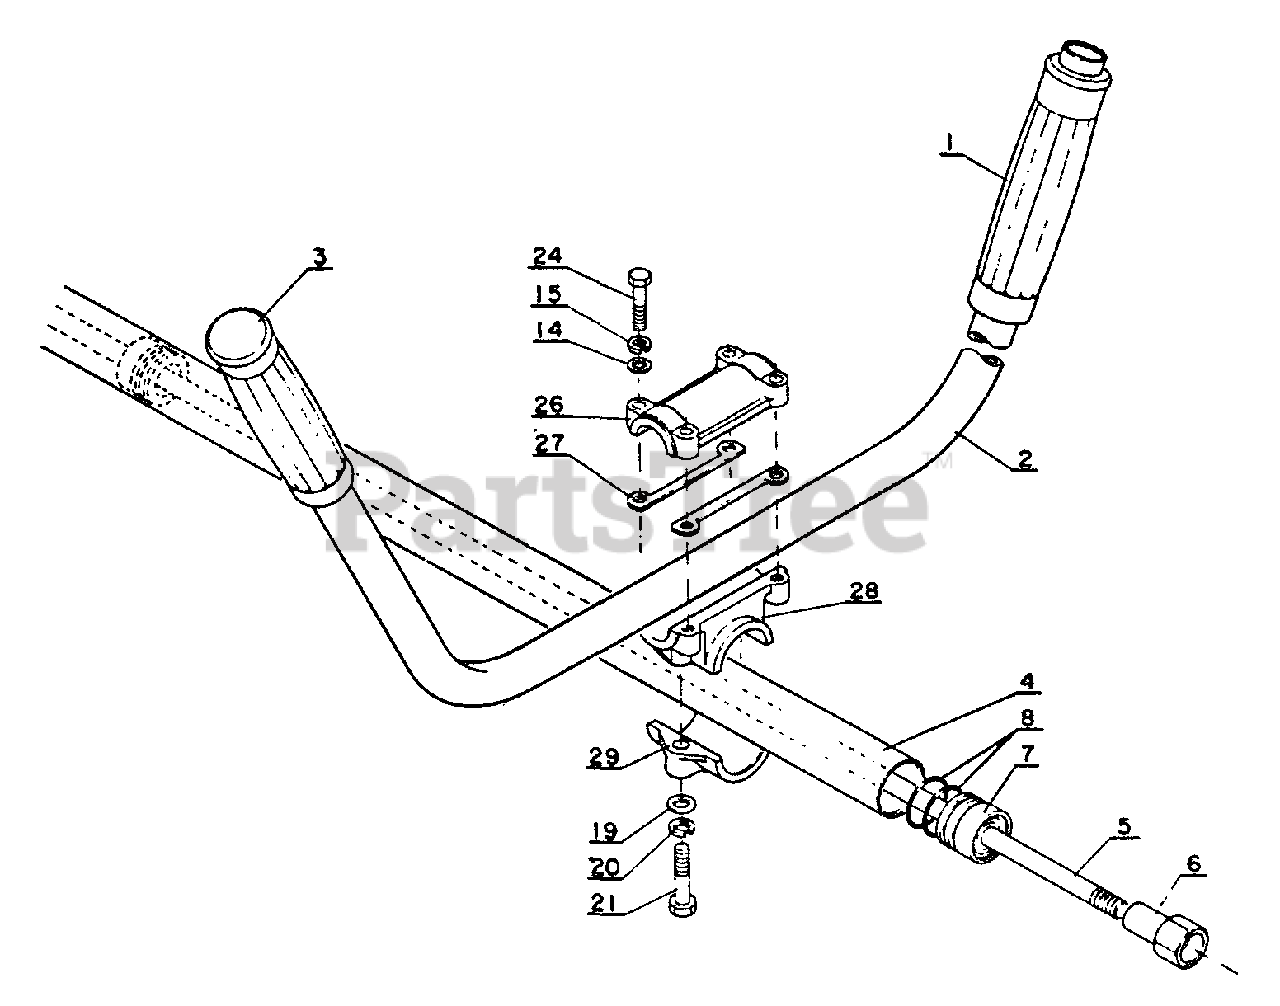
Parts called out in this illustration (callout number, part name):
1	U-HANDLE
2	GRIP, HANDLE
3	GRIP, HANDLE
4	PIPE, MAIN
5	DRIVESHAFT
6	DRIVESHAFT
7	STOPPER
8	O-RING 22
14	WASHER, FLAT 5.5×10×0.8
15	WASHER, SPRING 5
19	WASHER 6.5×11.5×0.8
20	WASHER, SPRING 6
21	BOLT - 6×32
24	BOLT - 5×25
26	BRACKET ASSY, HANDLE
28	BRACKET ASSY, HANDLE
29	BRACKET ASSY, HANDLE
